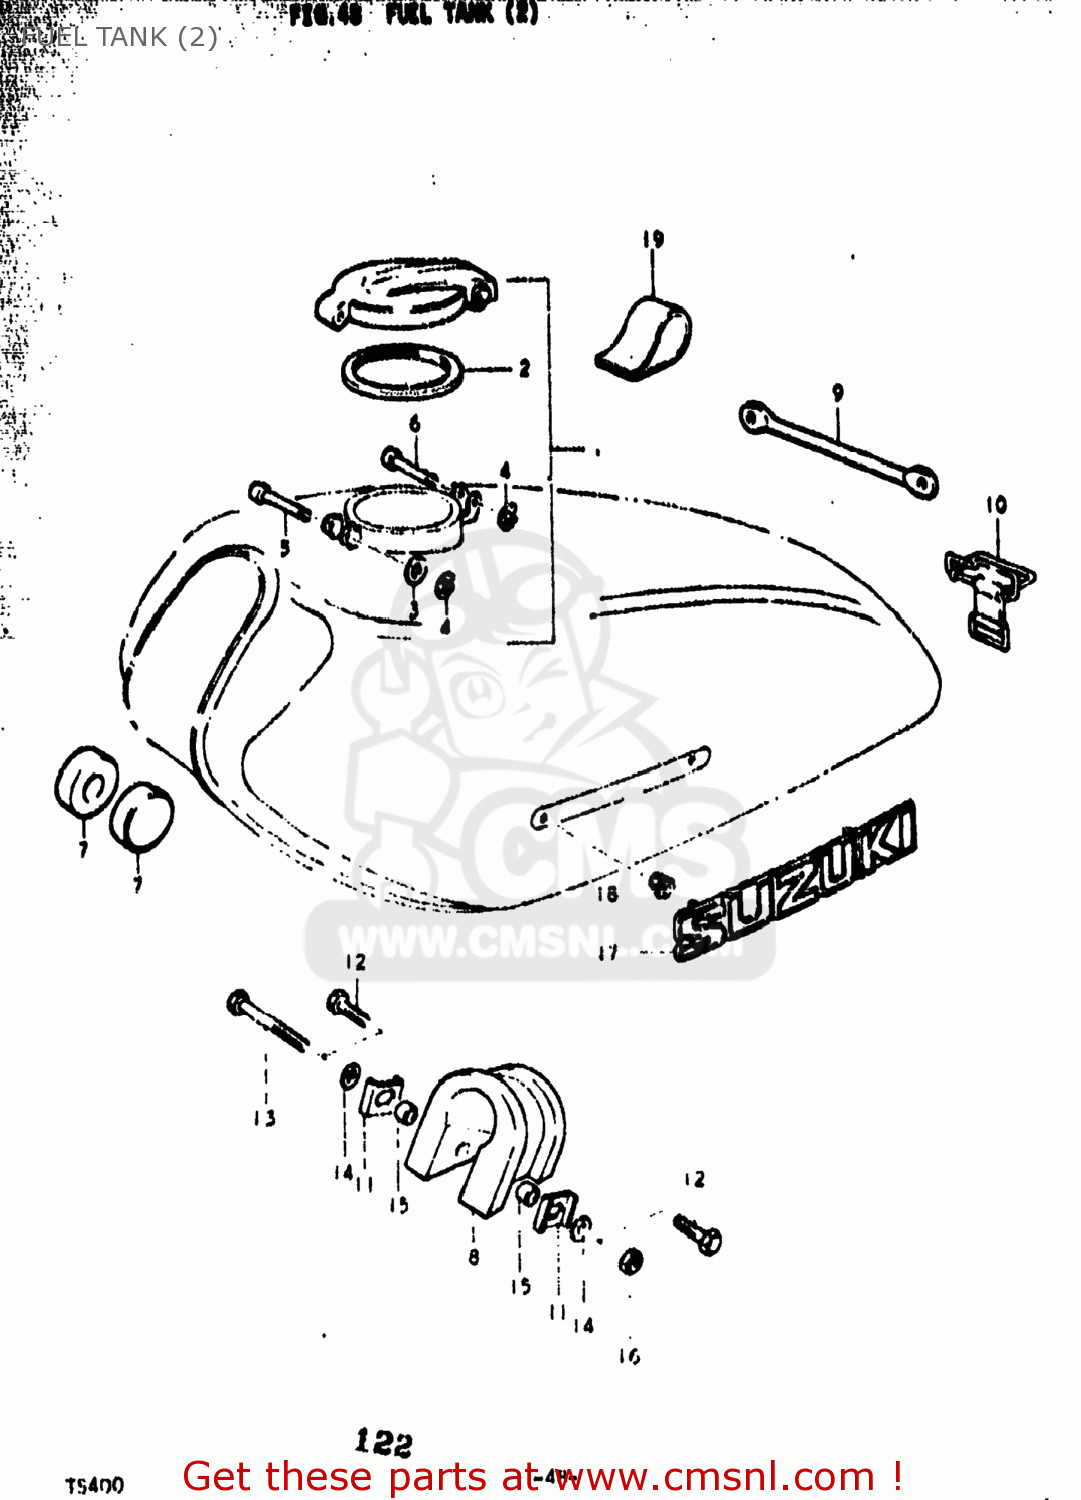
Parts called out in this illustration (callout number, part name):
1	CAP ASSEMBLY,FUEL TANK
2	GASKET (NAS)
3	WASHER
4	E RING
6	PIN,FUEL TANK C
7	CUSHION
8	CUSHION,FUEL TANK,REAR
9	BAND
10	BAND
11	CLIP
12	BOLT
13	BOLT
14	WASHER 6MM
15	SPACER (6.1X8X5.2)
16	NUT
17	EMBLEM
18	NUT
19	CUSHION,FUEL TANK
